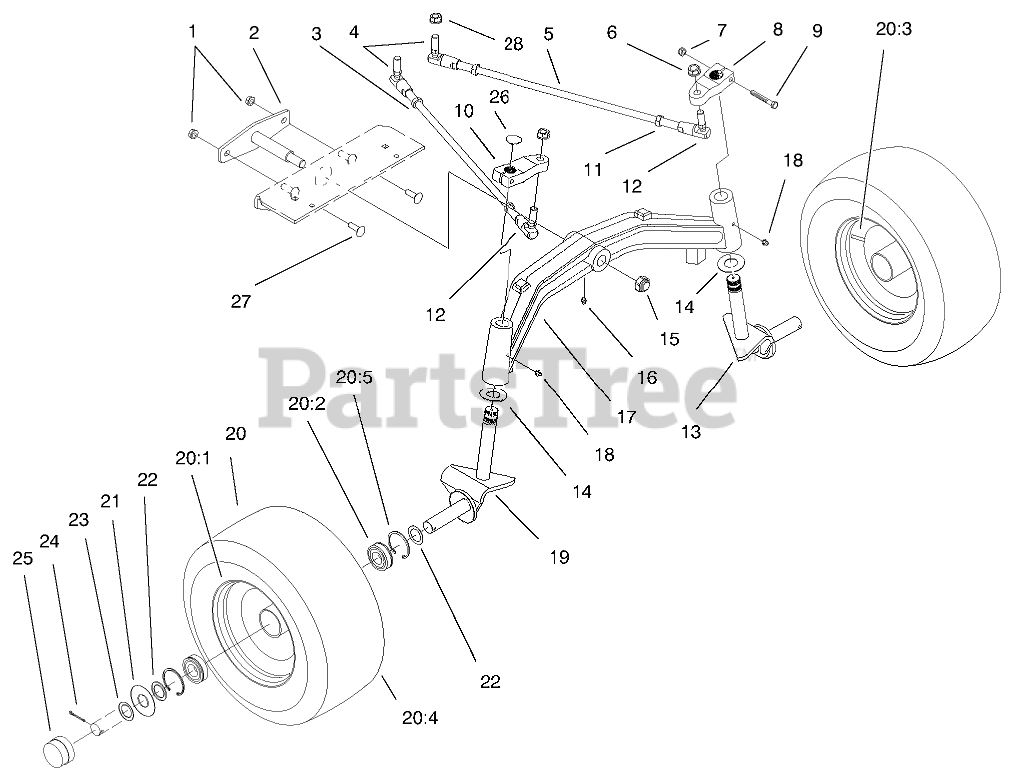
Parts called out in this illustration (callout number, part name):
1	NUT-LOCK, NI
2	Pin-Pivot
3	NUT-JAM
4	BALLJOINT-THREAD, LH
5	Rod-Steering
6	NUT-LOCK
7	NUT-LOCK, NI
8	ARM-STEERING, LH
9	SCREW-HH
10	ARM-STEERING, RH
11	NUT-HJ (LH THREAD)
12	BALLJOINT-THREAD. RH
13	SPINDLE-LH
14	WASHER-THRUST
15	NUT-LOCK
16	FITTING-LUBE, 45 DEG
17	AXLE-FRONT
18	FITTING-GREASE
19	SPINDLE-RH
20	Wheel & Tire ASM (Only On: 73550)
20	Wheel & Tire ASM (Only On: 73551)
20:1	RIM ASM
20:2	Bearing ASM (Incl. Ref. #20:5)
20:3	VALVE
20:4	Tire (Only On: 73550)
20:4	Tire (Only On: 73551)
20:5	Ring-Snap
21	WASHER-WHEEL
22	Washer
23	WASHER
24	PIN-COTTER
25	CAP-DUST
26	CAP - SPINDLE
27	BOLT-CARR
28	NUT-LOCK
